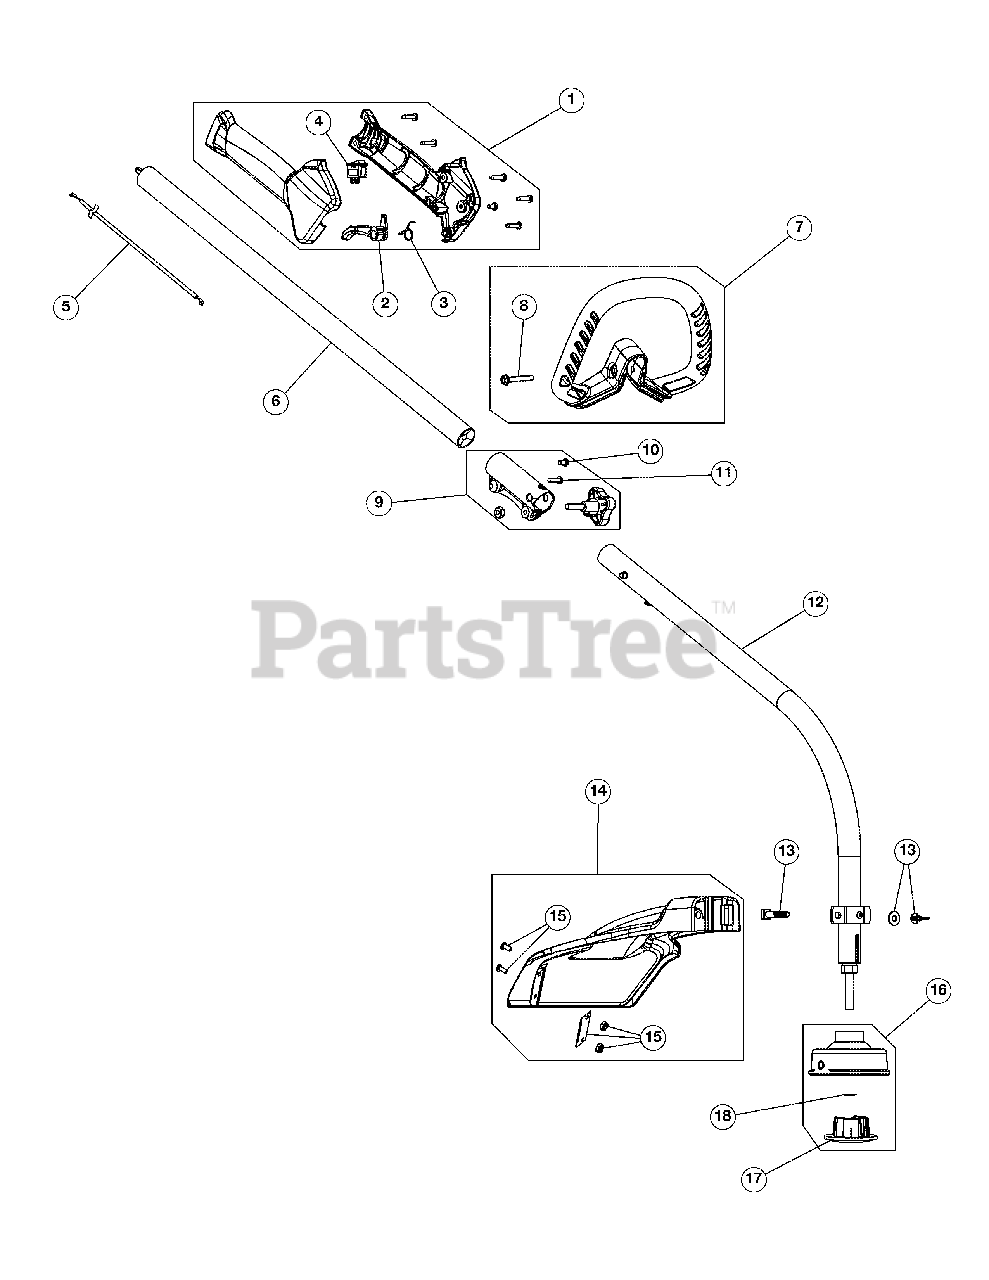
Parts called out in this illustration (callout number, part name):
1	Throttle Housing Assembly (Incl. 2-4)
2	Throttle Trigger
3	Throttle Trigger Spring
4	Switch Assembly
5	Throttle Cable Assembly
6	Upper Drive Shaft Assembly
7	D-Handle Assembly (Incl. 8)
9	Split Boom Coupler (Incl. 10-11)
10	Coupler Anti-Rotation Screw
11	Coupler Bolt
12	Lower Drive Shaft Housing
13	Shield Mount Hardware
14	Shield Assembly (Incl. 15)
15	Blade Assembly
16	Cutting Head Assembly (Incl. 17 & 18)
17	Cutting Head Cap
18	Push Nut
